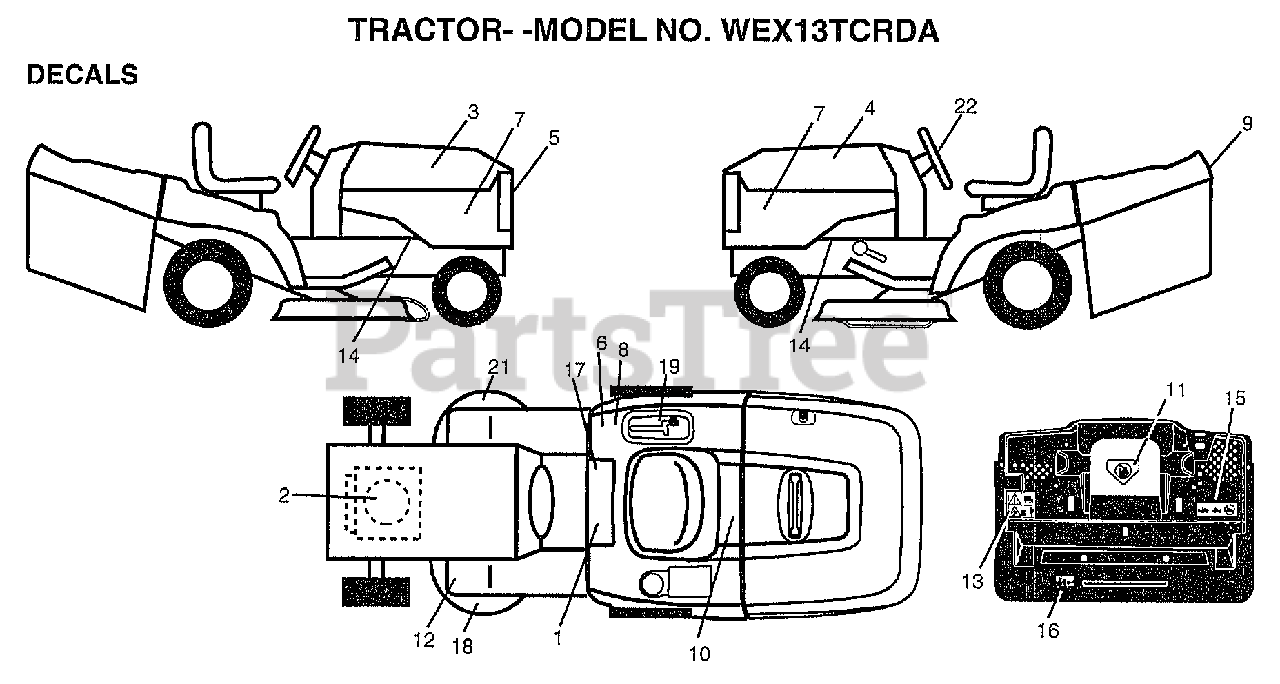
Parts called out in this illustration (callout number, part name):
1	DECAL.READ.O.MANU
2	DECAL HP ENGINE
3	DEECAL.HOOD.RH
4	DECAL.HOOD.LH
5	DECAL, GRILLE LENS
8	DECAL.EURO.ST.CE.
9	DECAL.FENDER.LOGO
10	DECAL.BATRY.3-3908
11	DECAL.DANGER.CUTF
12	DECAL-BRAKE/CLUTC
13	DECAL.WARNING.BACKPLATE.CRD
14	"DECAL CHASSIS,HOT"
15	DECAL, OPER BAG
16	DECAL.DRAWBAR.LDL
17	DECAL BRAK PARK
18	DECAL, DECK GRASSEATER
19	DECAL.CONSOLE.6SP.CRD
21	DECAL.DECK.HEX.BELT
22	DECAL, INS STRG WH
